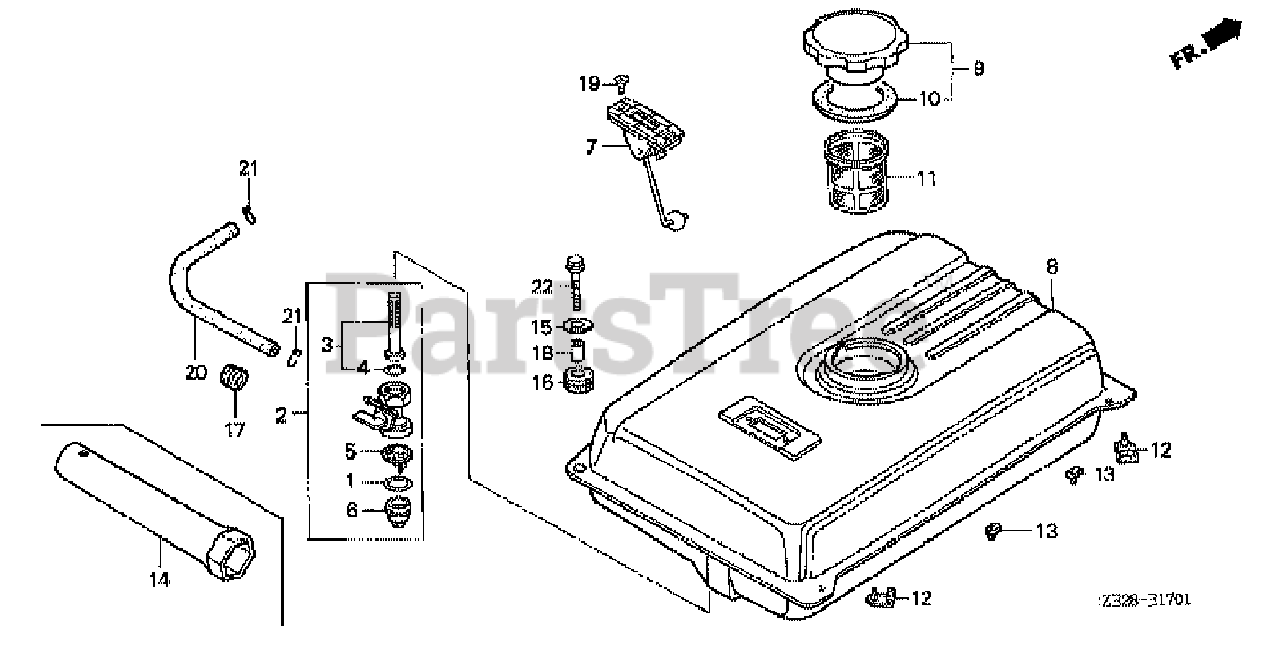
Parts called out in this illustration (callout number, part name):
1	GASKET, FUEL STRAINER CUP
2	PETCOCK ASSY.
3	SCREEN, FUEL STRAINER
4	O-RING (9X1.3)
5	FILTER, CUP
6	CUP, FUEL STRAINER
7	METER ASSY., FUEL
8	TANK, FUEL *T68* (TSURUI BLUE)
8	TANK, FUEL *Y131* (LIGHTNING YELLOW)
9	CAP, FUEL TANK
10	GASKET, FUEL FILLER CAP
11	FILTER, FUEL
12	RUBBER, TANK MOUNTING
13	STOPPER, DISCHARGE GUARD
14	WRENCH, PLUG
15	WASHER, TANK RUBBER
16	CUSHION, TANK RUBBER
17	RUBBER, FUEL TUBE
18	COLLAR, TANK RUBBER
19	SCREW, FLAT (5X10)
20	BULK HOSE, FUEL (4.5X3000) (4.5X180)
20	BULK HOSE, FUEL (4.5X3000) (4.5X260)
21	CLIP, TUBE (B8)
22	BOLT, FLANGE (6X22)
